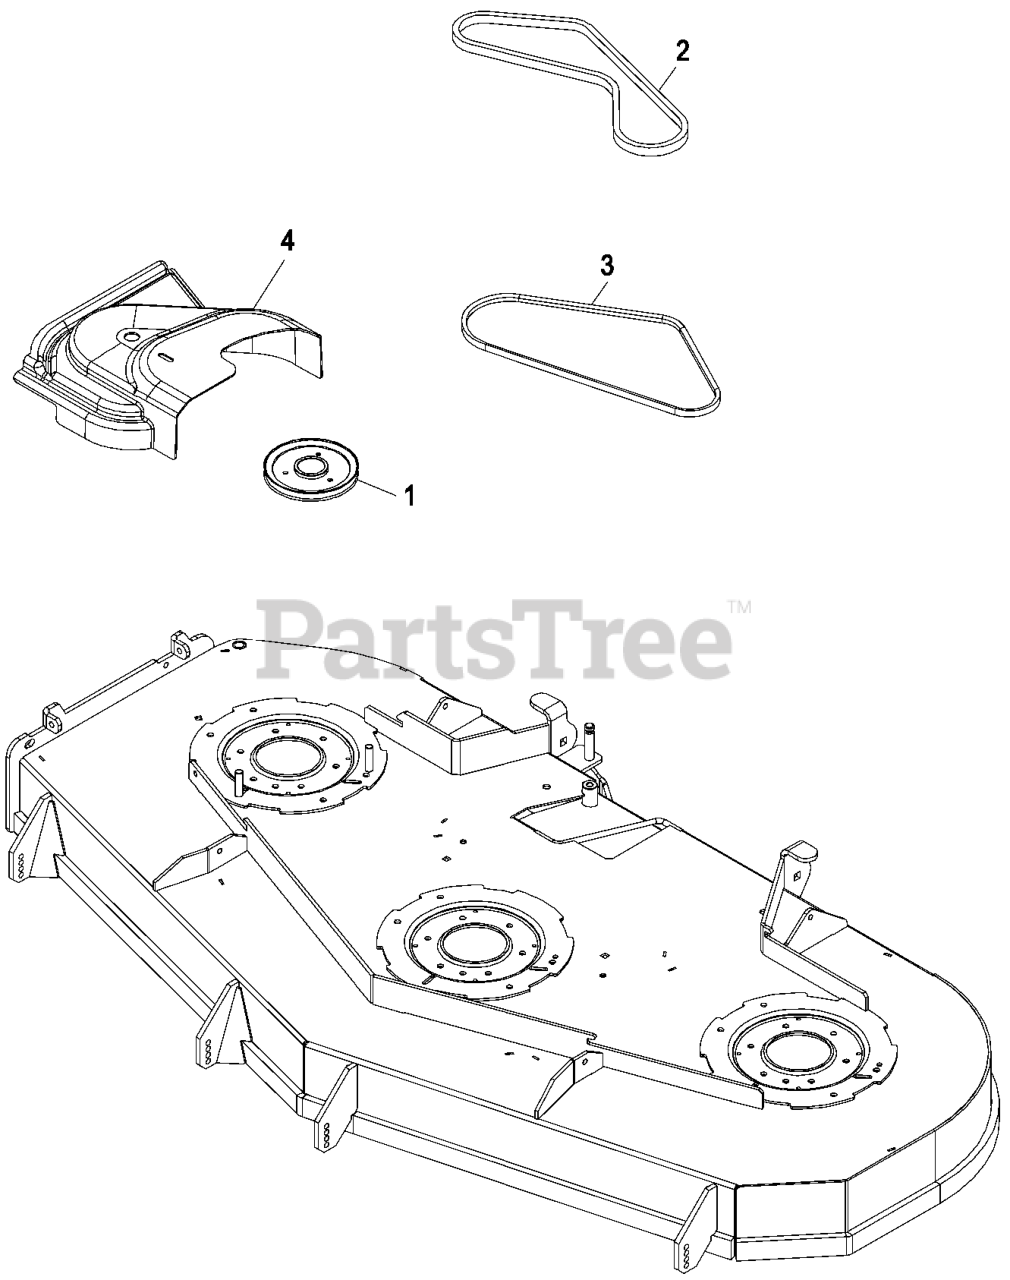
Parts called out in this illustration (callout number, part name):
1	SHEAVE,DRIVE LZUV 606
3	BELT, BLOWER DRIVE 60
4	COVER,BELT UV 60
